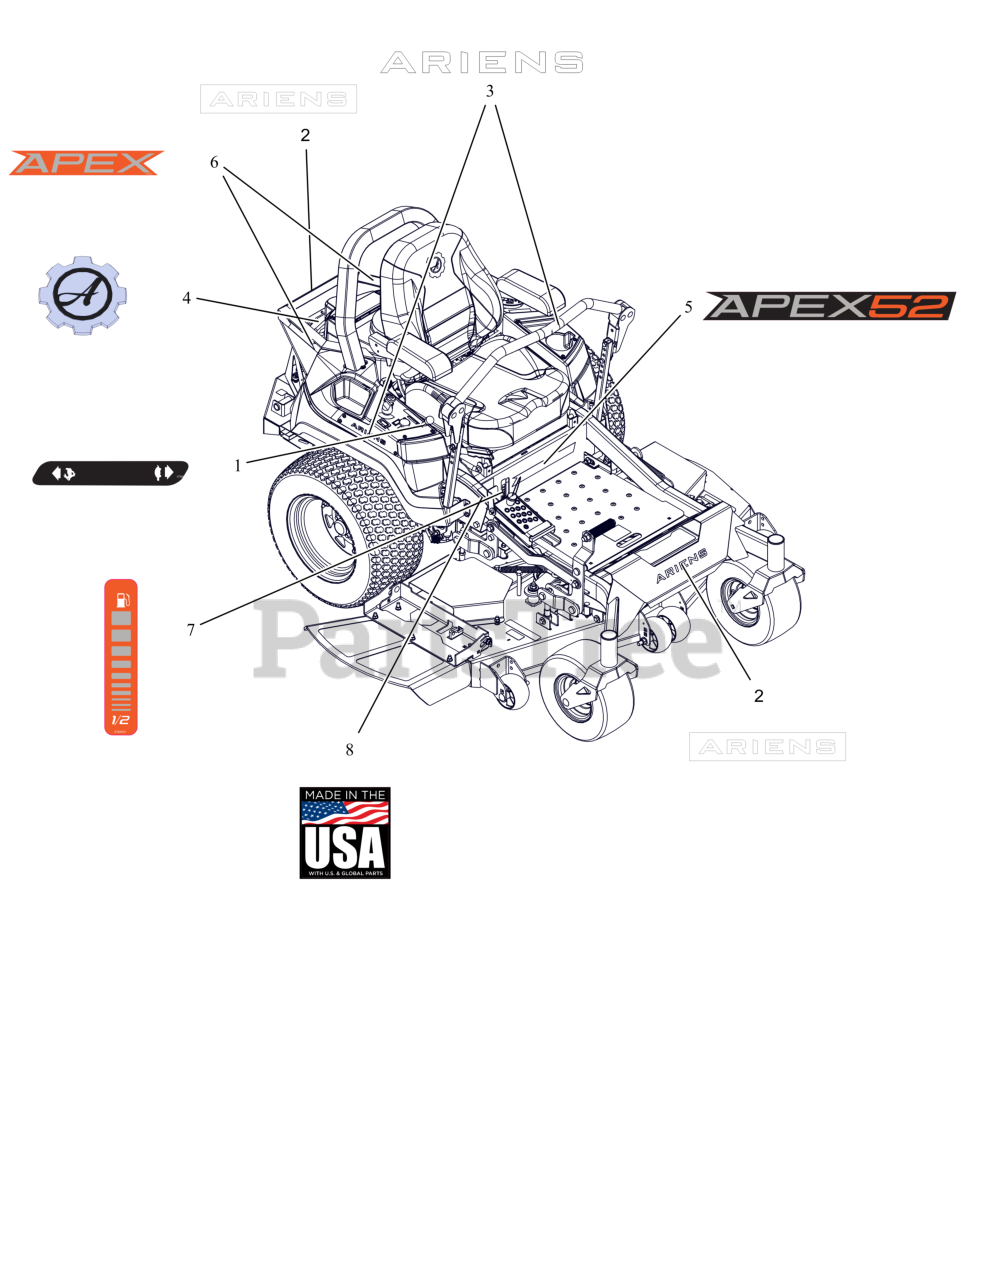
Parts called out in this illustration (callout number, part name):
1	DECAL, DASH DECAL
2	DECAL - ARIENS 9.625"
3	DECAL, ARIENS (6.50")
4	DECAL, ARIENS-GEAR BADGE -THK
5	DECAL, 52" APEX KICKPLATE
6	DECAL, APEX FENDER
7	DECAL, ARIENS FUEL LEVEL
8	DECAL, MADE IN USA
